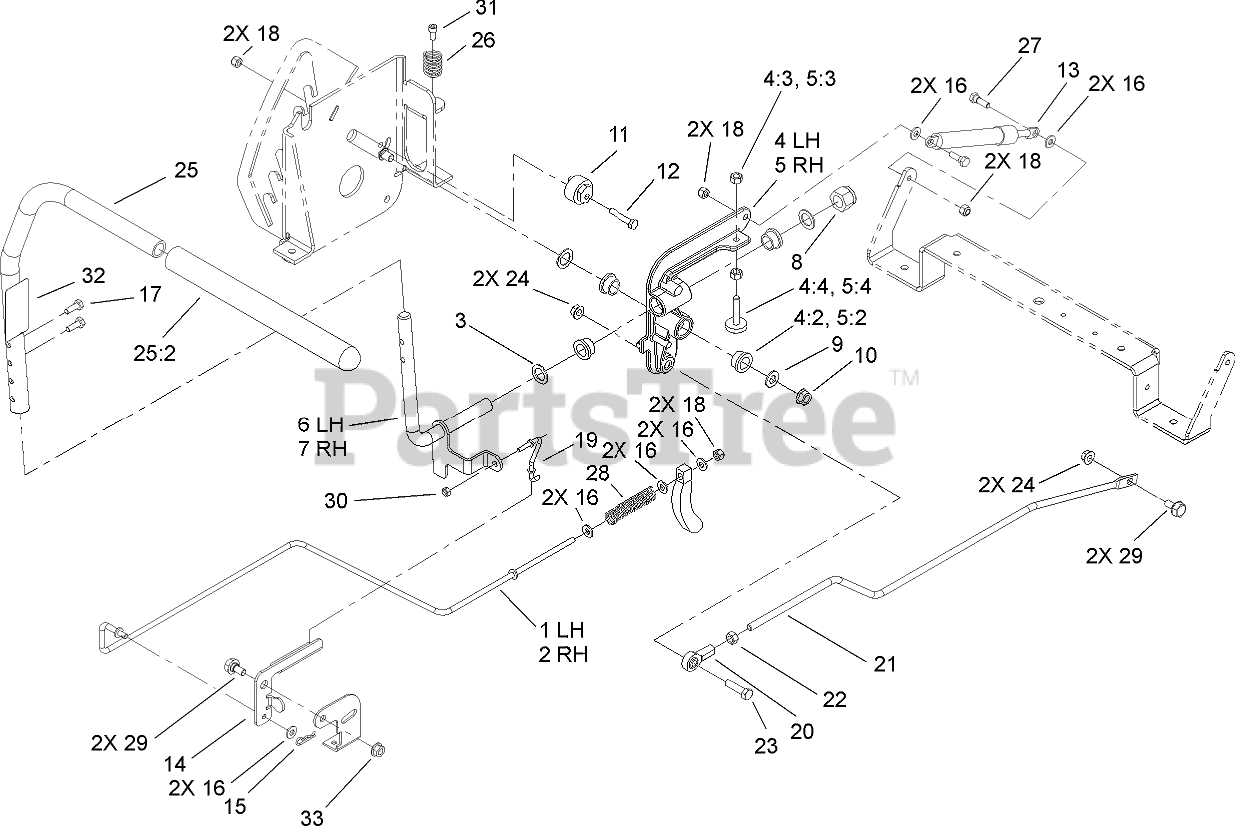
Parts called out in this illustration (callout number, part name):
2	ROD-BRAKE, RH
3	WASHER-THRUST
5	RH ACTIVATOR ARM ASM
5:2	BUSHING
5:3	NUT-HEX
5:4	STOP-ADJUSTMENT
7	RH PIVOT SHAFT ASM
8	NUT-LOCK, NI
9	WASHER-FLAT
10	NUT-LOCK, NI
11	ECCENTRIC
12	SCREW-HH
13	Damper-Control, Motion
14	BELLCRANK
15	PIN-COTTER
16	WASHER-FLAT
17	SCREW-HH
18	NUT-LOCK, NI
19	LINK-BRAKE
20	BALLJOINT-RH
21	ROD-HYDRO
22	NUT-HEX
23	SCREW-HH
24	NUT-HF
25	HANDLE ASM
25:2	GRIP-CONTROL, MOTION
26	SPRING-COMPRESSION
27	BOLT-SHOULDER
28	SPRING-COMPRESSION
29	BOLT-SHOULDER
30	NUT-LOCK, NI
31	SCREW-HSH
33	NUT-HF
